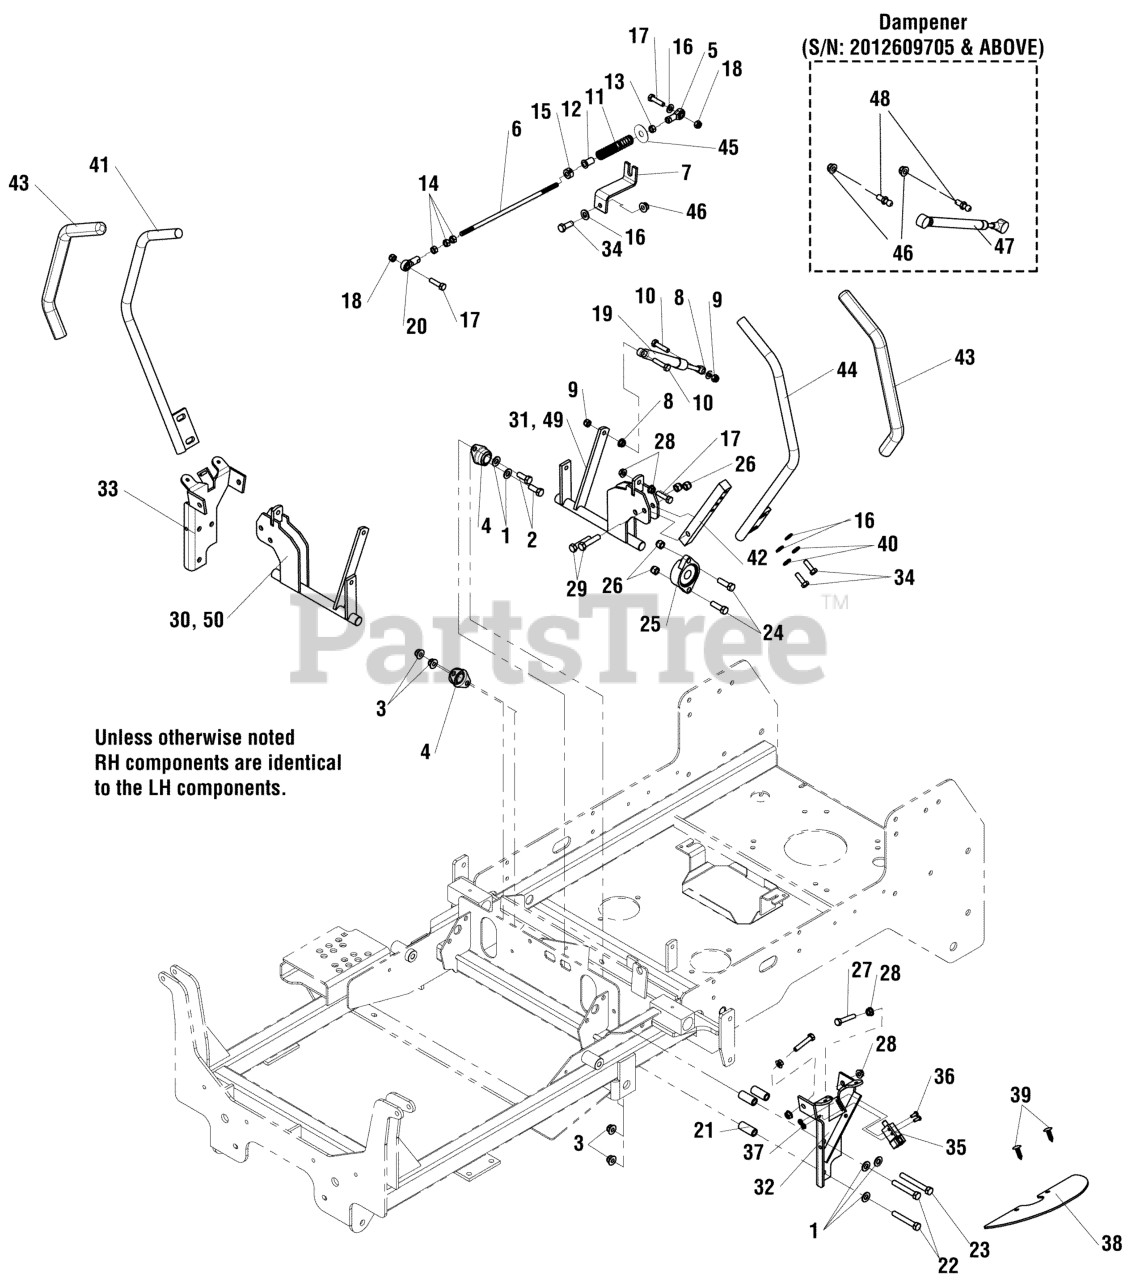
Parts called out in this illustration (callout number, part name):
1	WASHER, 3/8 SAE
2	BOLT, 3/8-16 X 1" GD5 CZ
3	NUT, 3/8-16 HEX NYLOCK FLANGE
4	BEARING, BRONZE FLANGE 3/4"
5	BALL JOINT 5/16-24 LH FEMALE BRONZE RACE
6	ROD, HYDRO LINKAGE
7	MOUNT, REVERSE RETURN - BLK
8	NUT, M8-1.25 SERR. FLANGE, CZ
9	NUT, M8-1.25 NYLON LOCK, CZ
10	BOLT, M8-1.25 X 35MM, GD8.8
11	SPRING, REVERSE RETURN
12	BUSHING, NYLON
13	NUT, 5/16 HEX LH
14	NUT, HEX 5/16-24
15	COLLAR, 5/16" SET
16	WASHER, 5/16" SAE
17	BOLT, 5/16-18 X 1-1/4" GD5 YZ
18	NUT 5/16-18 HEX NYLON LOCK
19	DAMPENER
20	BALL JOINT 5/16-24 RH FEMALE BRONZE RACE
21	SPACER, .63 X .39 X 1.50
22	BOLT, 3/8-16 X 2-1/2" GD5 CZ
23	BOLT, 3/8-16 X 3" GD5 CZ
24	BOLT, 3/8-16 X 1-1/4" GD5 CZ
25	BEARING, FLANGE
26	NUT, 3/8-16 HEX NYLON LOCK
27	BOLT, 5/16-18 X 1-3/4" GD5 TFL
28	NUT, 5/16-18 HEX SERRATED FLANGE (SMALL)
29	BOLT, 3/8-16 X 1-3/4" GD5 CZ
30	WELD, CONTROL SHAFT - RH - RED
31	WELD, CONTROL SHAFT - LH - RED
32	WELD, NEUTRAL LOCK, LH - BLK
33	WELD, NEUTRAL LOCK, RH - BLK
34	BOLT, 5/16-18 X 1" GD5 YZ
35	SWITCH, PLUNGER, N.O.
36	SCREW, #10-24 X 1/2" ROUND SLOTTED
37	NUT, #10-24 HEX
38	GUARD, RUBBER MOTION CONTROLS
39	PUSH RIVET (TREE TYPE) BLACK
40	WASHER, 5/16 LOCK CZ
41	WELD, HANDLE MOTION CONTROL RH - BLK
42	MOUNT, CONTROL ARM - BLK
43	GRIP, FOAM, 3/4" ID, 16" LONG
44	WELD, HANDLE MOTION CONTROL LH - BLK
45	WASHER, 3/8 X 1" X 1/16, NYLON F/W
46	NUT, 5/16-18 HEX NYLON FLANGE
47	DAMPENER, CONTROL
48	10MM BALL STUD, 5/16-18 X 3/4
49	WELD, CONTROL SHAFT, LH - BLK
50	SHAFT, Control
